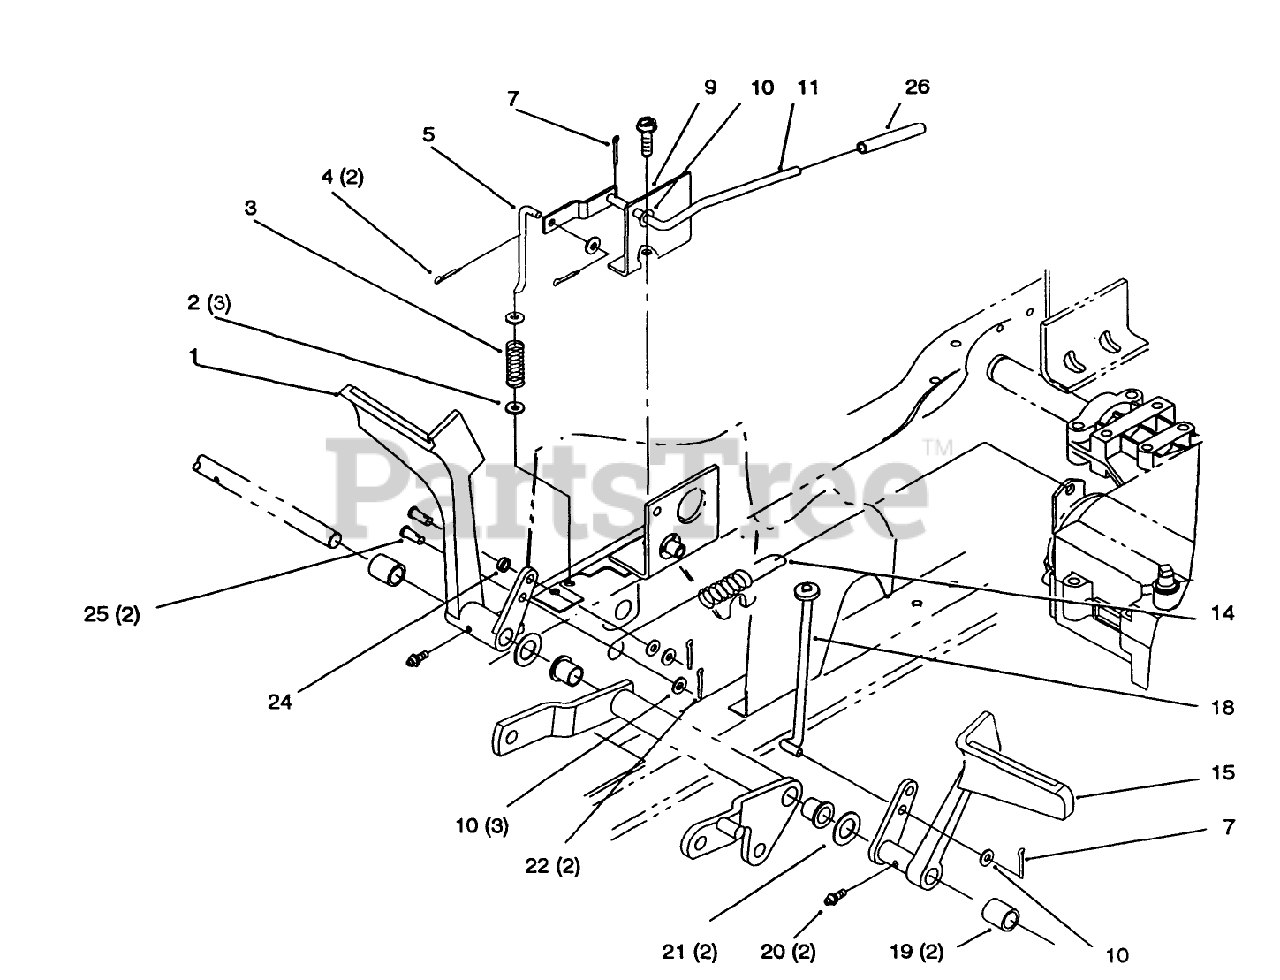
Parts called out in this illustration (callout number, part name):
1	Pedal-Brake (Only On: 72042, 72062)
2	WASHER-FLAT
4	PIN-COTTER
5	ROD - PARKING BRAKE
7	PIN-COTTER
10	WASHER-PLAIN
11	PARK BRAKE LVR WA*B
15	PEDAL-CLUTCH
18	CLUTCH ROD WA
19	SPACER
20	FITTING-GREASE
21	WASHER-WAVE
22	PIN-COTTER
24	BUSHING
25	PIN-CLEVIS
26	GRIP - PARKING BRAKE
